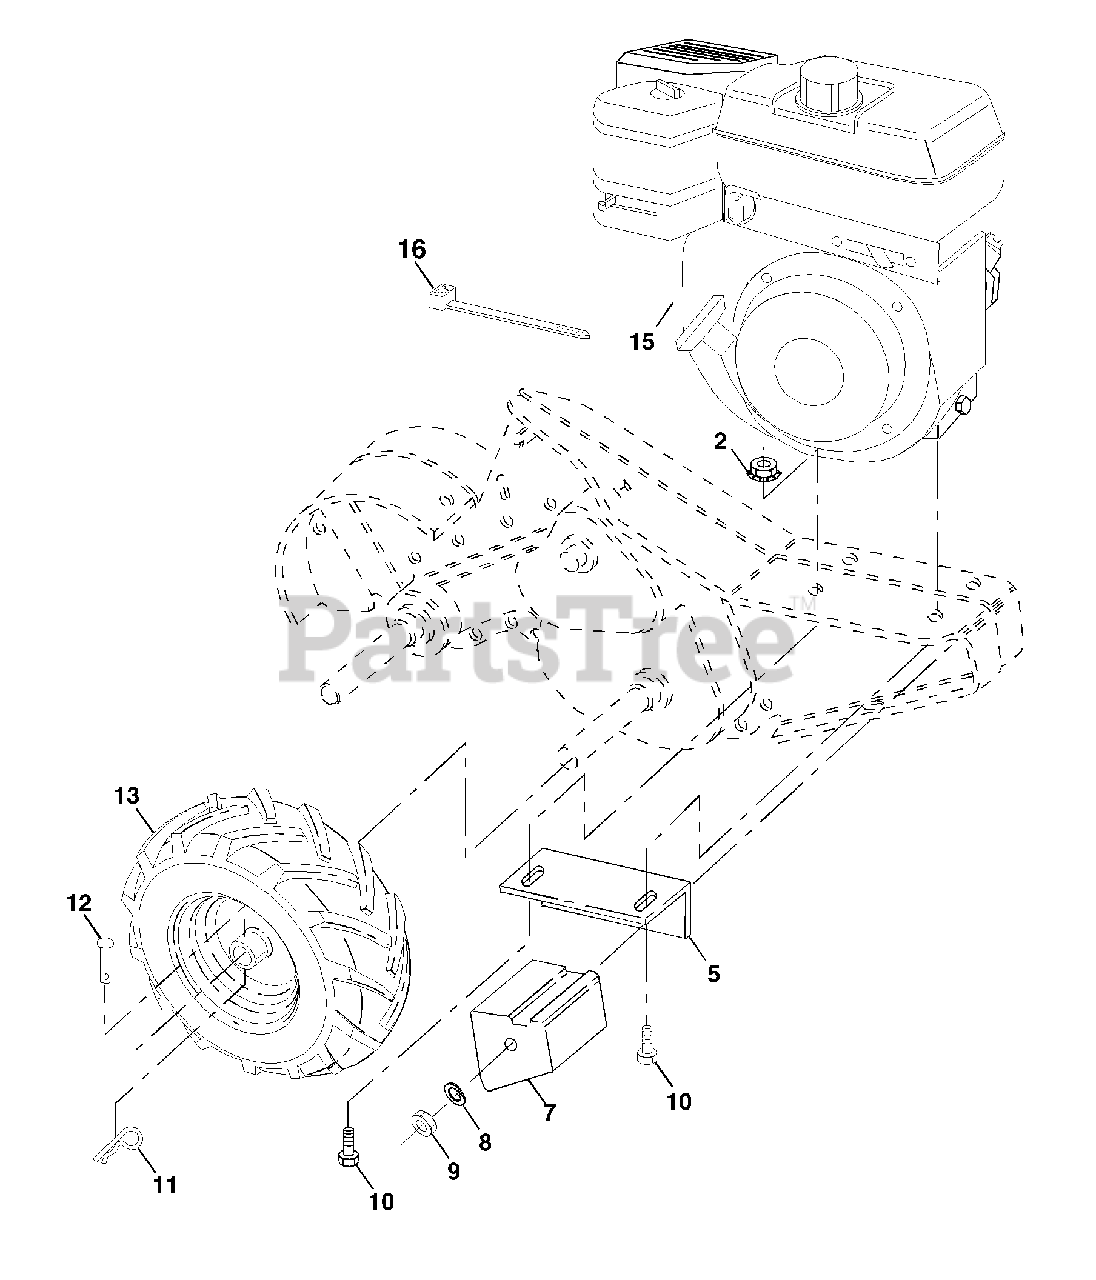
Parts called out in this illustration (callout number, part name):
2	Nut, Lock Hex Flange
5	Bracket, Reinforcement
7	Counter Weight, R.H.
8	Washer, Lock 3/8
9	Nut, Hex 3/8-16
10	Bolt, Hex 5/16-18 x 1-1/2
11	Clip, Hairpin
12	Rivet, Drilled
13	Tire
13	Tire Valve
16	Tie Cable
